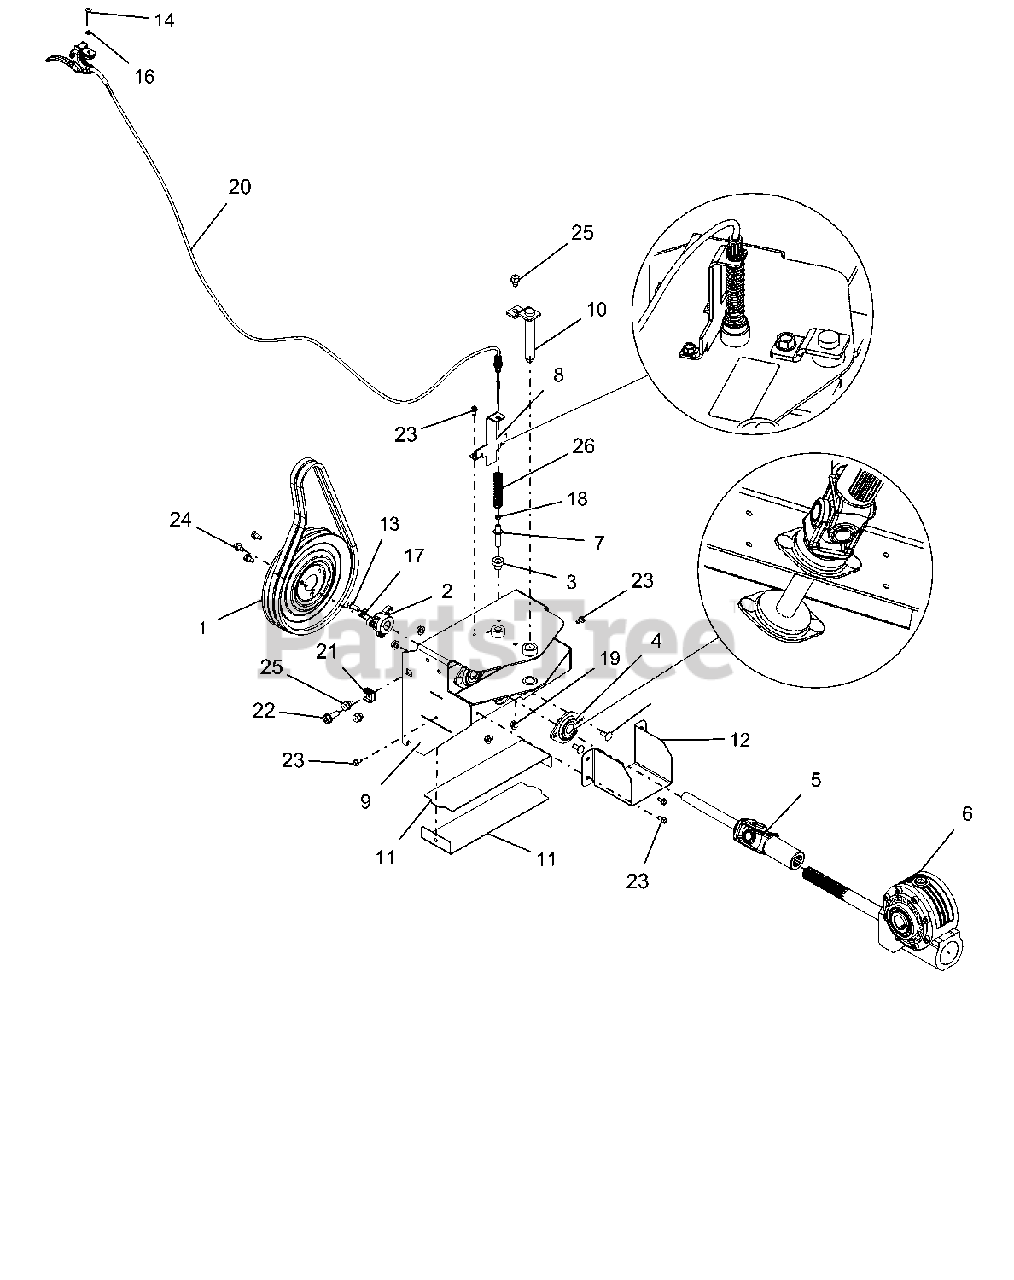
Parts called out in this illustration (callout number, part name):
1	PULLEY, SPIN FORM DUAL GROOVE
2	PULLEY HUB, BOLT-ON D-BORE .75
3	SPACER -FLANGED .390X.500X.781
4	BEARING, 2 BOLT FLANGE -.75 ID
5	DRIVELINE, SERIES 07 (U-JOINT)
6	GEARBOX, WORM - 8.25:1
7	PIN, ADJUSTABLE ANGLE BRUSH
8	BRKT, PIN HOLDER
9	ADAPTER, BRUSH
10	WLDMT, BRUSH PIN
11	GUARD, BRUSH PTO
12	GUARD, BRUSH U-JOINT
13	BLT-HEX .31-24X.75 YWZC GR5
14	SCR-MCH .25-20X1.50 OVAL HD
15	@BLT-RDHDSQNK .31-18X.75 G5YZ
16	WSHR-LK-INT .250 TH TYA
17	WSHR-LK .312X.097 HVY YWZC
18	@NUT-HEX 10-24 YWZC
19	@NUT-LK-TOP-FLG .31-18 YWZC
20	CABLE, REMOTE BRUSH LOCK
21	NUT-RETNR .38-16 TINRMAN
22	BLT-SERHFWH .375-16X1.0 YWZC
23	SCR-TAP .25-20X.50 HWH TR YWZ
24	@SCR-TAP .31-18X.50 HWH TR YWZ
25	@SCR-TAP .38-16X.50 HWH TR YWZ
26	SPRING, COMPRESSION
